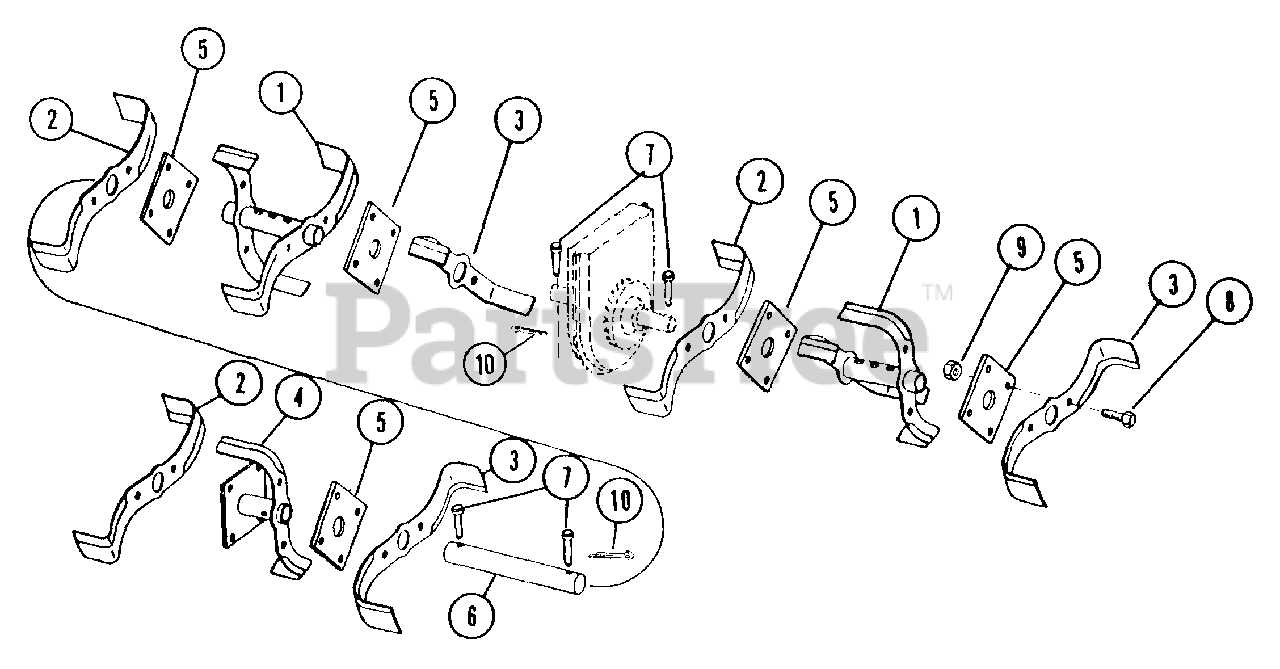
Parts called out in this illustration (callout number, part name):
1	INNER TINE
2	L H TINE
3	R H TINE
4	TINE EXTENTION
5	TINE PLATE
6	SHAFT EXTENSION
7	CLEVIS PIN
8	BLT-HEX .44-14X1.00 GR5
9	NUT-LK-TOP .437-14 GR C PL
10	PIN-COTR .12X1.0 PL
